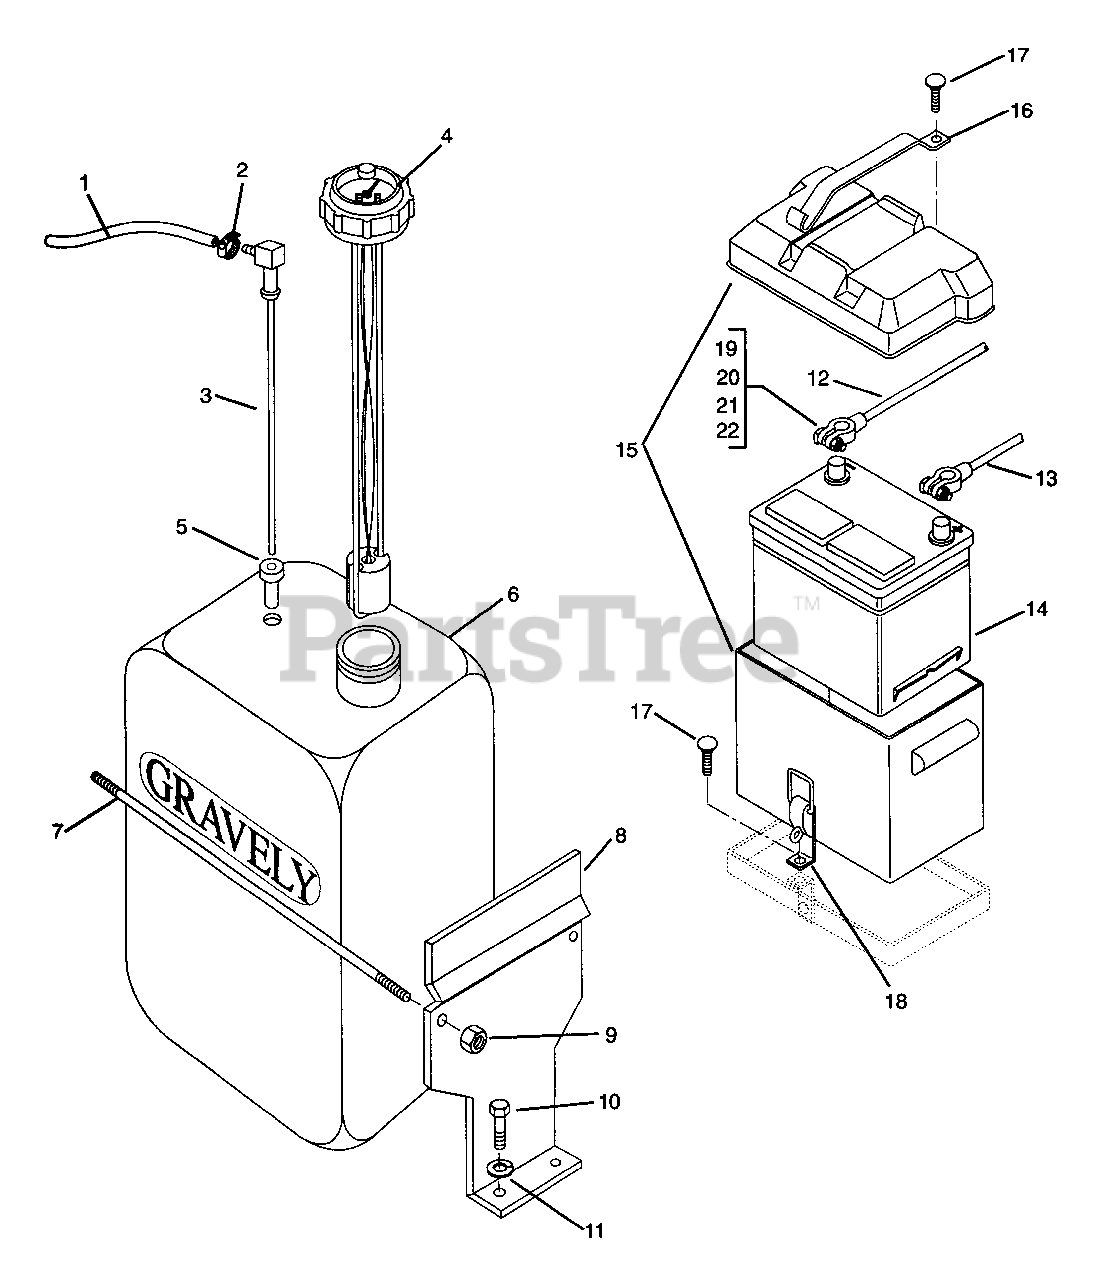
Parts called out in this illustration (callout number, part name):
1	Gas Line - Bulk
2	Hose Clamp
3	Fitting, Tank
4	Gauge, Fuel
6	Tank, Fuel
7	Rod, Tank
8	Weldment, Tank Bracket
9	Nut-Locking-Center .31 - 18
10	Bolt-Hex .31-18 x .50-Grade 5
11	Washer-Locking .31 x .078
12	Negative Battery Cable
13	Positive Battery Cable
14	Battery, Marine Type
15	Battery Box
16	Strap, Battery Hold-Down
17	Bolt-Round Head Square Neck .31-18 x 1.75-Grade 5
18	Latch Assembly-Battery Hold-Down
19	Bolt-Hex .25-20 x .75-Grade 5
20	Washer-Flat-Steel .312 x .734 x .065
21	Washer-Locking .25 x .062
22	Nut-Hex .25-20
